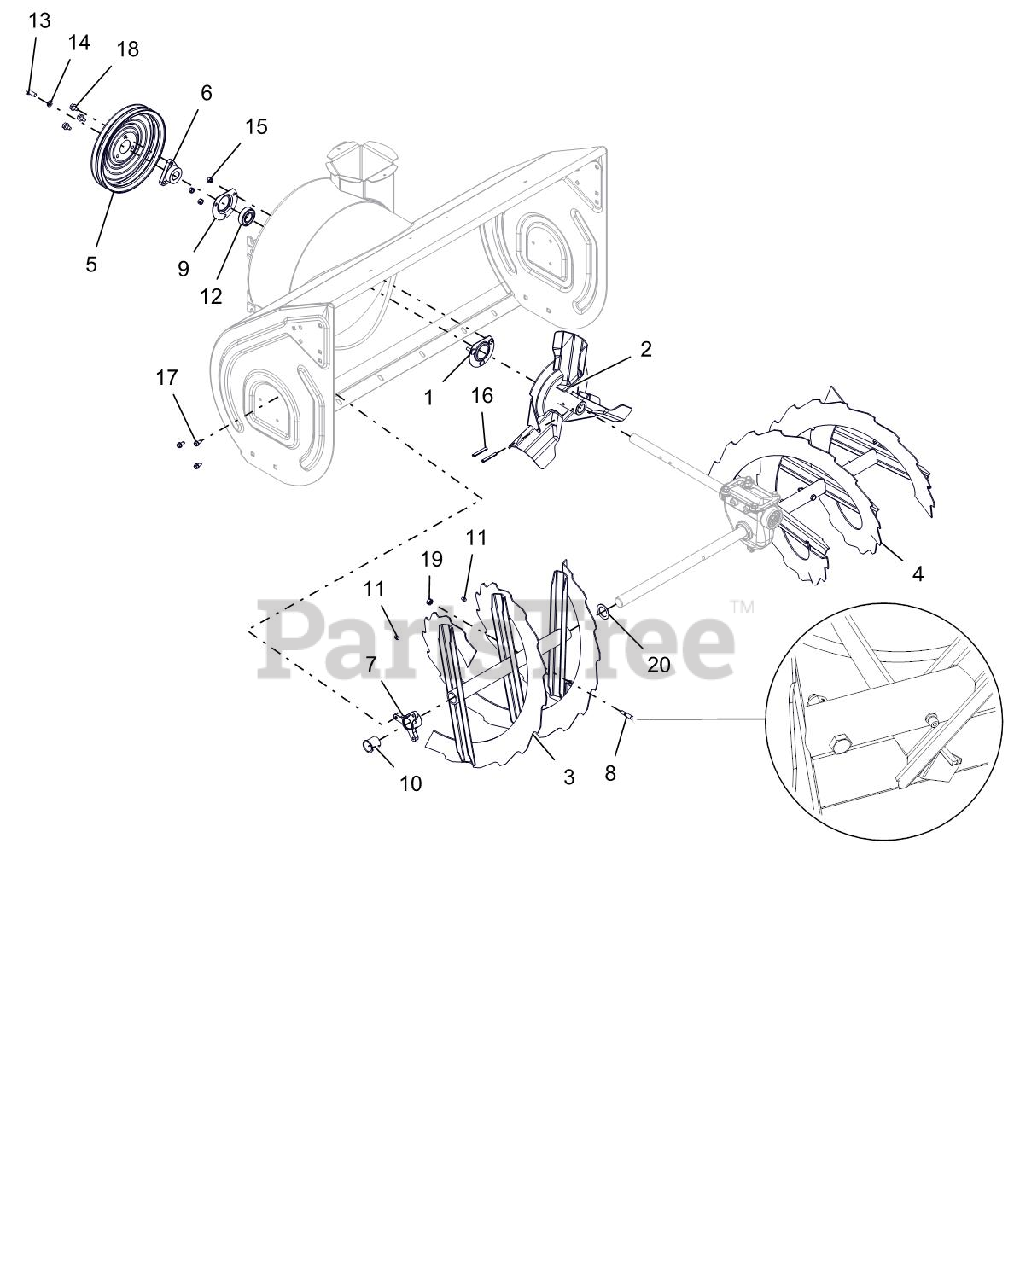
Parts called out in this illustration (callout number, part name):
1	BEARING FLANGE
2	IMPELLER, 3 BLADE-14"
3	RAKE, RH-36"(1 ID X 15.75 OD)
4	RAKE, LH-36" (1 ID X 15.75 OD)
5	PULLEY, SPIN FORM DUAL GROOVE
6	PULLEY HUB, D-BORE .87 PRO
7	BUSHING, RAKE SHAFT 1"
8	SHEAR BOLT SERVICE ASSEMBLY
9	BEARING FLANGE
10	BSHG-FLG SPLIT NYLINER 1.0" HP
11	ZERK,FITTING .25X.125 DRIVE IN
12	BRG-BALL .876X1.75X.50 RSTFP
13	BLT-HEX .31-24X.75 YWZC GR5
14	WSHR-LK .312X.097 HVY YWZC
15	@NUT-LK-CTR .25-20 YWZC
16	PIN-ROLL .250X1.75
17	SCR-TAP .25-20X.50 HWH TR YWZ
18	@SCR-TAP .31-18X.50 HWH TR YWZ
19	@NUT-LK-CTR .31-18 YWZC
20	WSHR-FL-STL 1.010X1.505X.062YZ
